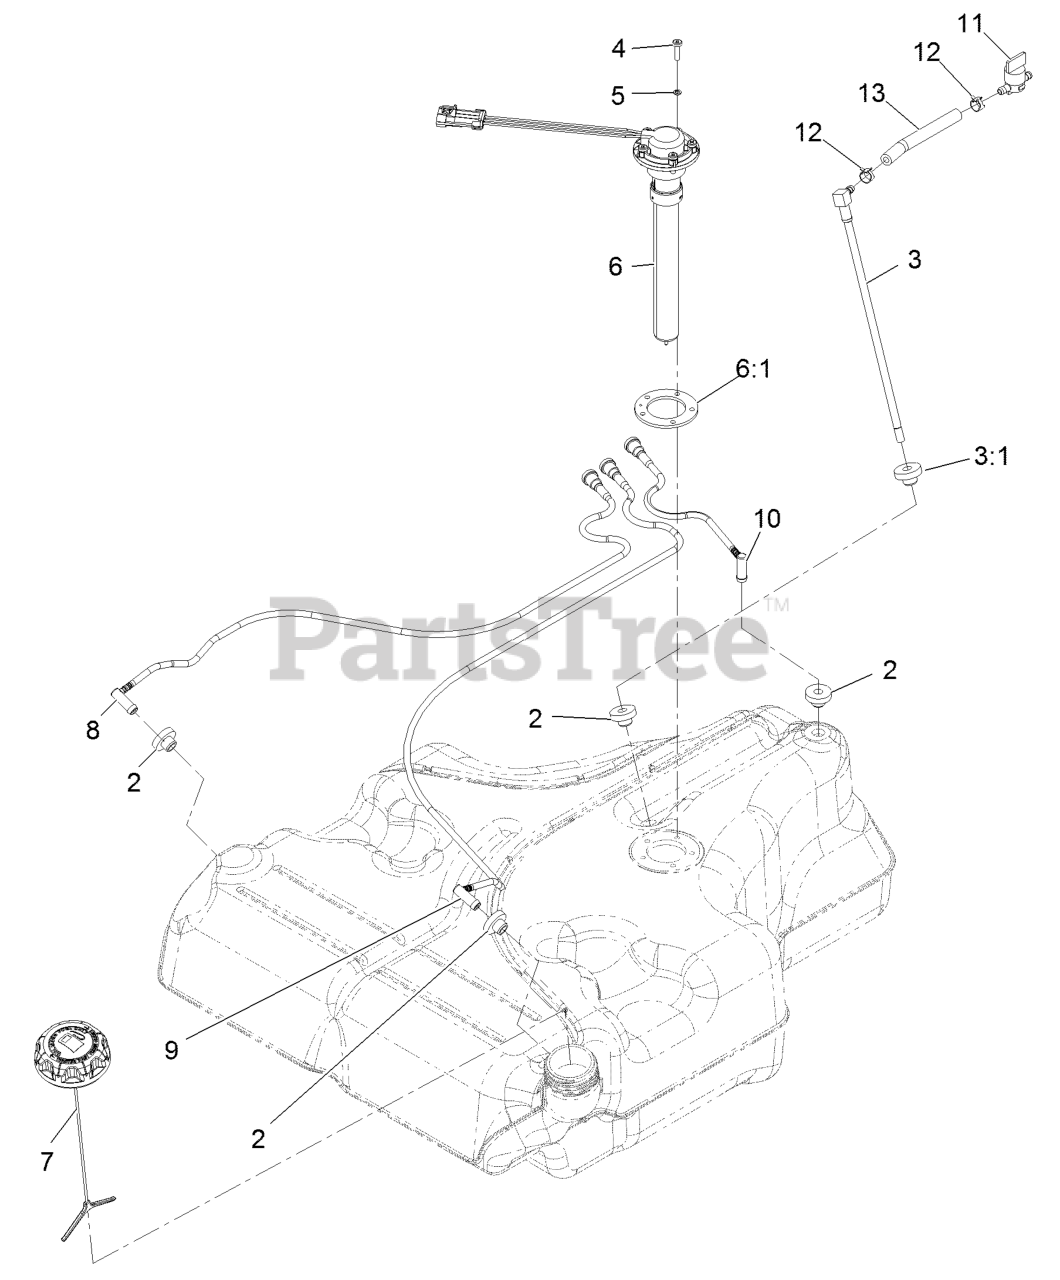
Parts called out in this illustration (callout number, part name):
2	BUSHING
3	FUEL LINE KIT (WITH GROMMET)
3:1	BUSHING
4	SCREW-PAN
5	WASHER-LOCK
6:1	GASKET-SENDER, FUEL
7	CAP-FUEL, RATCHETING
8	RH VENT LINE KIT (WITH GROMMET)
9	LH VENT LINE KIT (WITH GROMMET)
10	REAR VENT LINE KIT (WITH GROMMET)
11	VALVE-FUEL
12	CLAMP-HOSE
13	HOSE-FUEL
